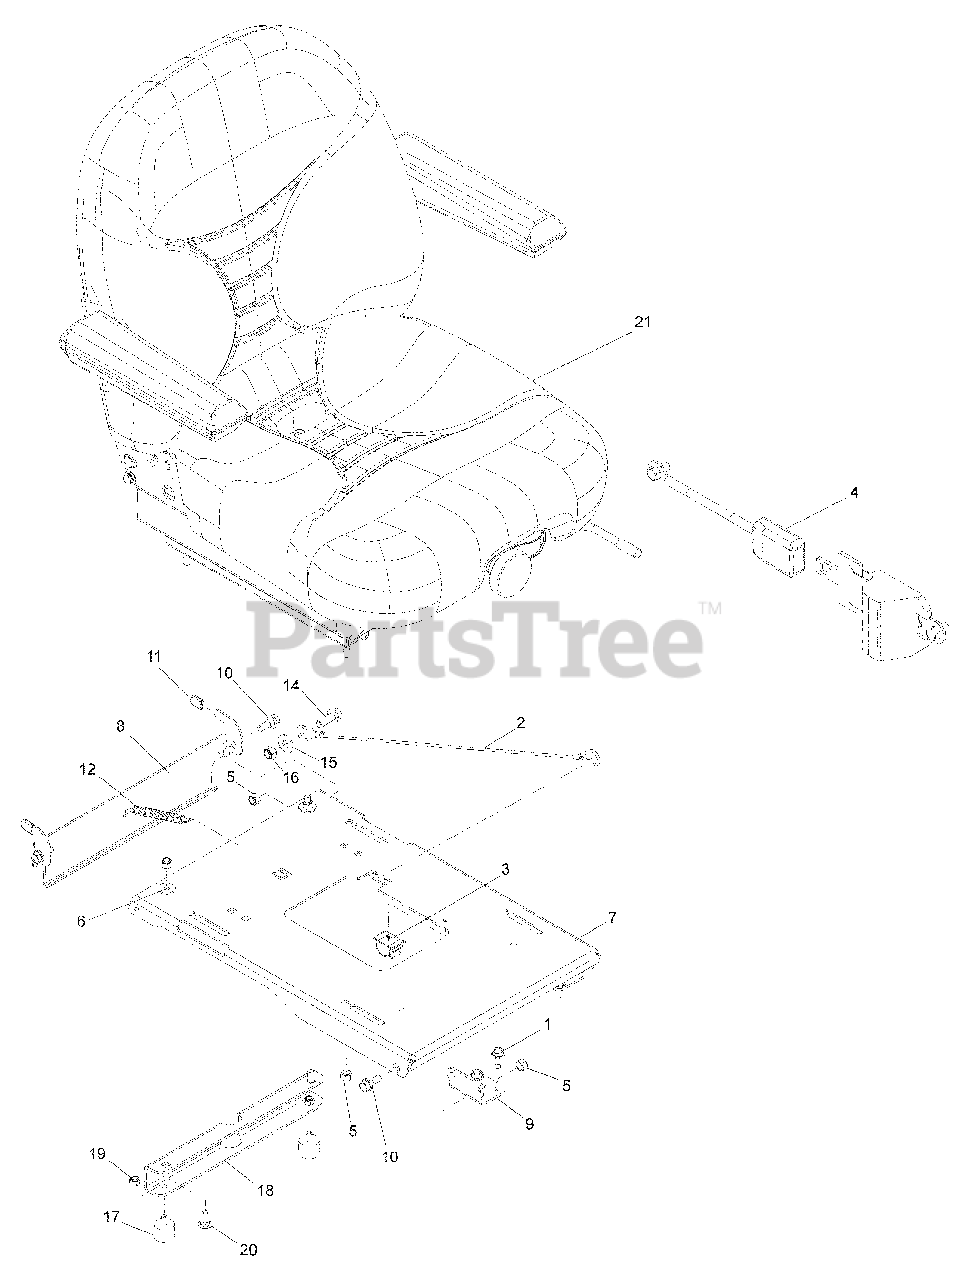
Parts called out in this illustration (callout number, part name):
1	BOLT 5/16-18 x ¾ THRD FRM
2	LANYARD, SEAT
3	CLIP, WIRE
4	SEAT BELT, RETRACTABLE
5	NUT 5/16-18 HEX NYLOC
6	WASHER 5/16 STD FLT
8	LATCH, SEAT
9	PIVOT, SEAT PAN
10	BOLT 5/16-18 HEX HD
11	GRIP, VINYL
13	HCS 5/16-18 x 1
14	HCS 3/8-16 x 1 WHIZLK
15	WASHER 3/8 FLAT STD
16	NUT 3/8-16 HEX NYLOC
17	STUD, PLATE MOUNT
18	STANDOFF, SEAT PAN
19	NUT ¼-20 HEX NYLOC
20	RHSNB 5/16-18 x ¾
